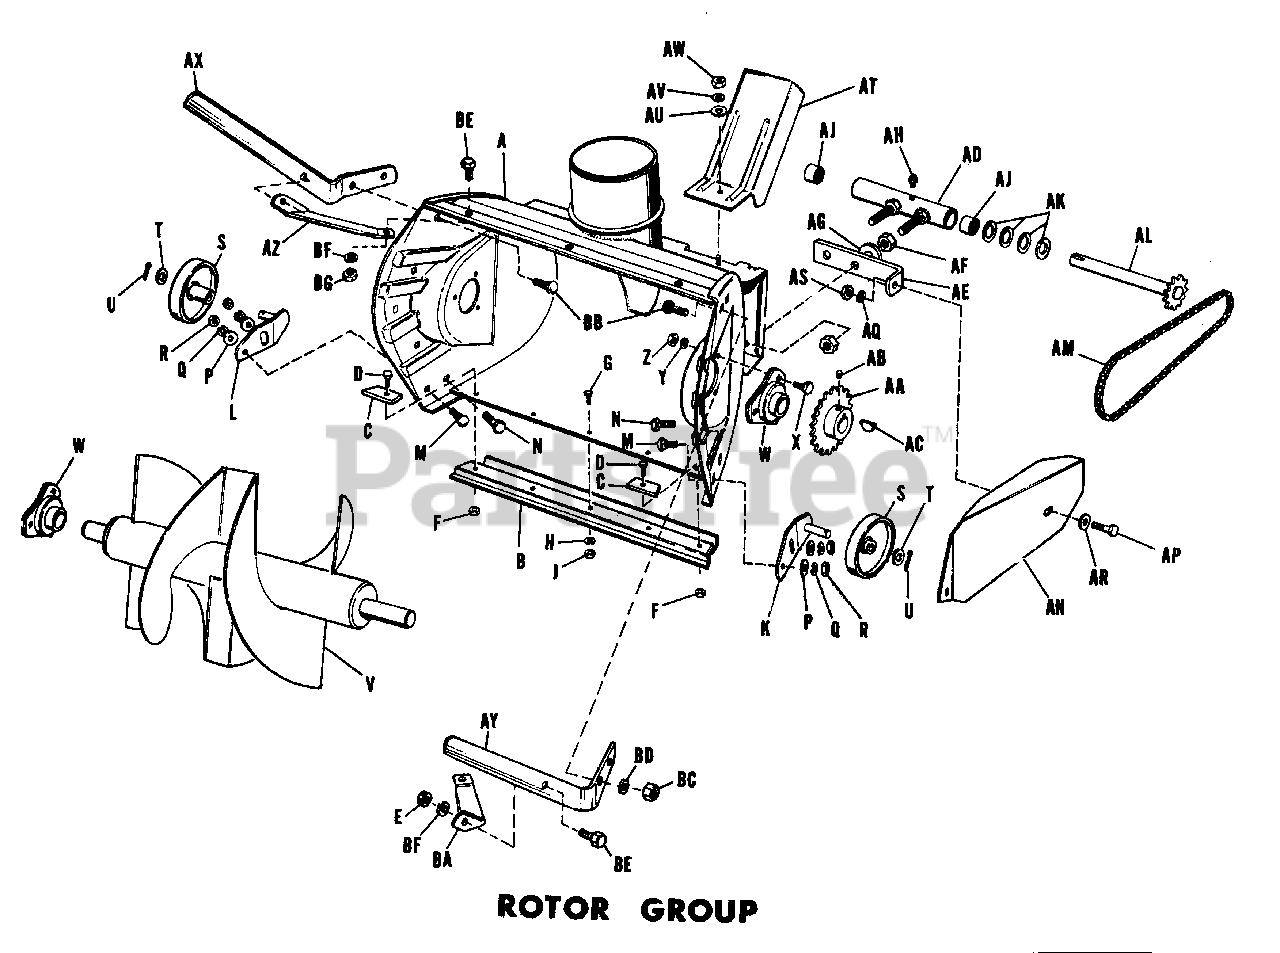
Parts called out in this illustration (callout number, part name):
A	Body Assembly
B	Scraper, Body
C	Clamp, Scraper
D	Capscrew, Hex, 5/16"-18 NC x 3/4" lg.
F	Nut, Hex, Full Lock, 5/16"-18 NC
G	Capscrew, Hex, 1/4"-20 NC x 5/8" lg.
H	Washer, Lock, 1/4"
J	Nut, Hex, Full, 1/4"-20 NC
K	Bracket Assembly, Roller, Left Hand
L	Bracket Assembly, Roller, Right Hand
M	Bolt, Carriage, 3/8"-16 NC x 3/4" lg.
N	Capscrew, Hex, 3/8"-16 NC x 7/8" lg.
P	Washer, Plain, 3/8"
Q	Washer, Lock, 3/8"
R	Nut. Hex Full, 3/8"-16 NC
S	Roller Assembly
U	Pin, Cotter, 1/8" x 1-1/4" lg.
V	Rotor Assembly
W	Bearing Assembly
X	Capscrew, Hex, 5/16"-18 NC x 3/4" lg.
Y	Washer, Lock, 5/16"
Z	Nut, Hex, Full, 5/16"-18 NC
AA	Sprocket, Rotor
AB	Set Screw, Socket Head, 5/16"-18 NC x 5/16" lg.
AC	Key, Hi-Pro
AD	Housing Assembly, Bearing
AE	Bracket, Chain Guard
AF	Nut, Hex, Full, 1/2"-13 NC
AG	Washer, Plain, 1/2"
AH	Fitting, Grease
AJ	Bearing, Needle
AL	Shaft Assembly
AM	Chain, Rotor
AN	Guard, Chain
AP	Capscrew, Hex, 5/16"-18 NC x 3/4" lg.
AQ	Washer, Lock, 5/16"
AR	Washer, Plain, 5/16"
AS	Nut, Hex, Full, 5/16"-18 NC
AT	Guard, Belt
AU	Washer, Plain, 3/8"
AV	Washer, Lock, 3/8"
AW	Nut, Hex, Full 3/8"-16 NC
